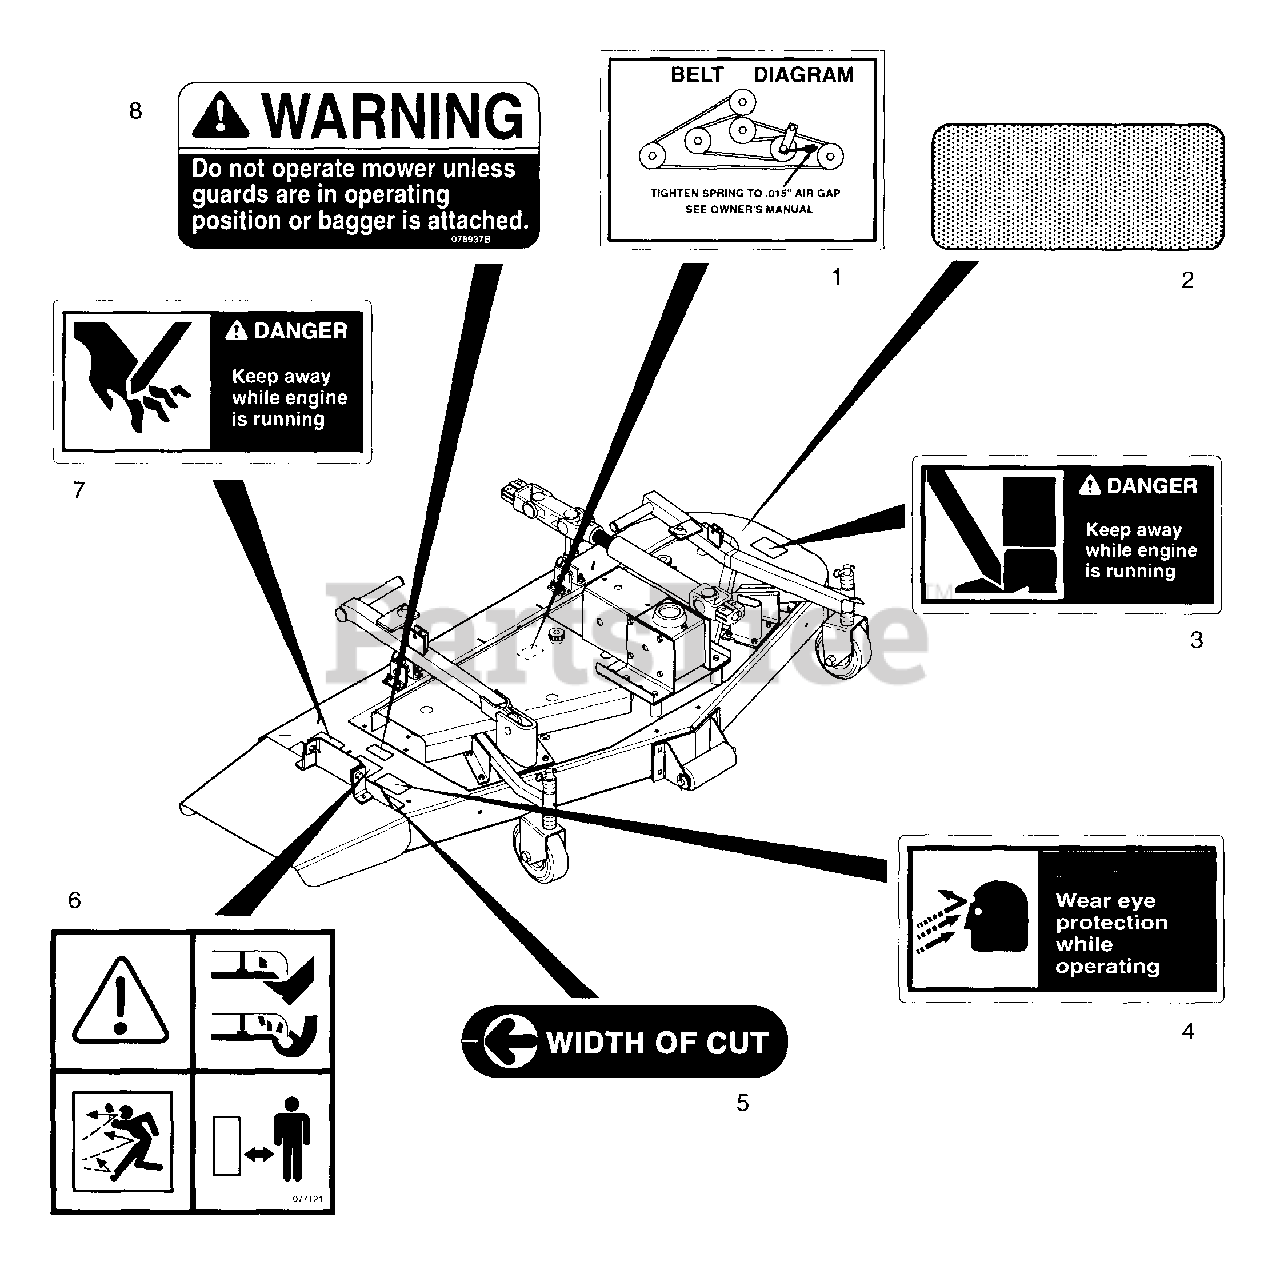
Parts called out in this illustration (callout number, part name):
1	Decal, Belt Diagram
2	Cover, Large Footboard
3	Decal, Danger Foot
4	Decal, Warning Eye
5	Decal, Width of Cut
6	Decal-Mower Pan Foreign
7	Decal, Danger Hand
8	Decal, Warning
